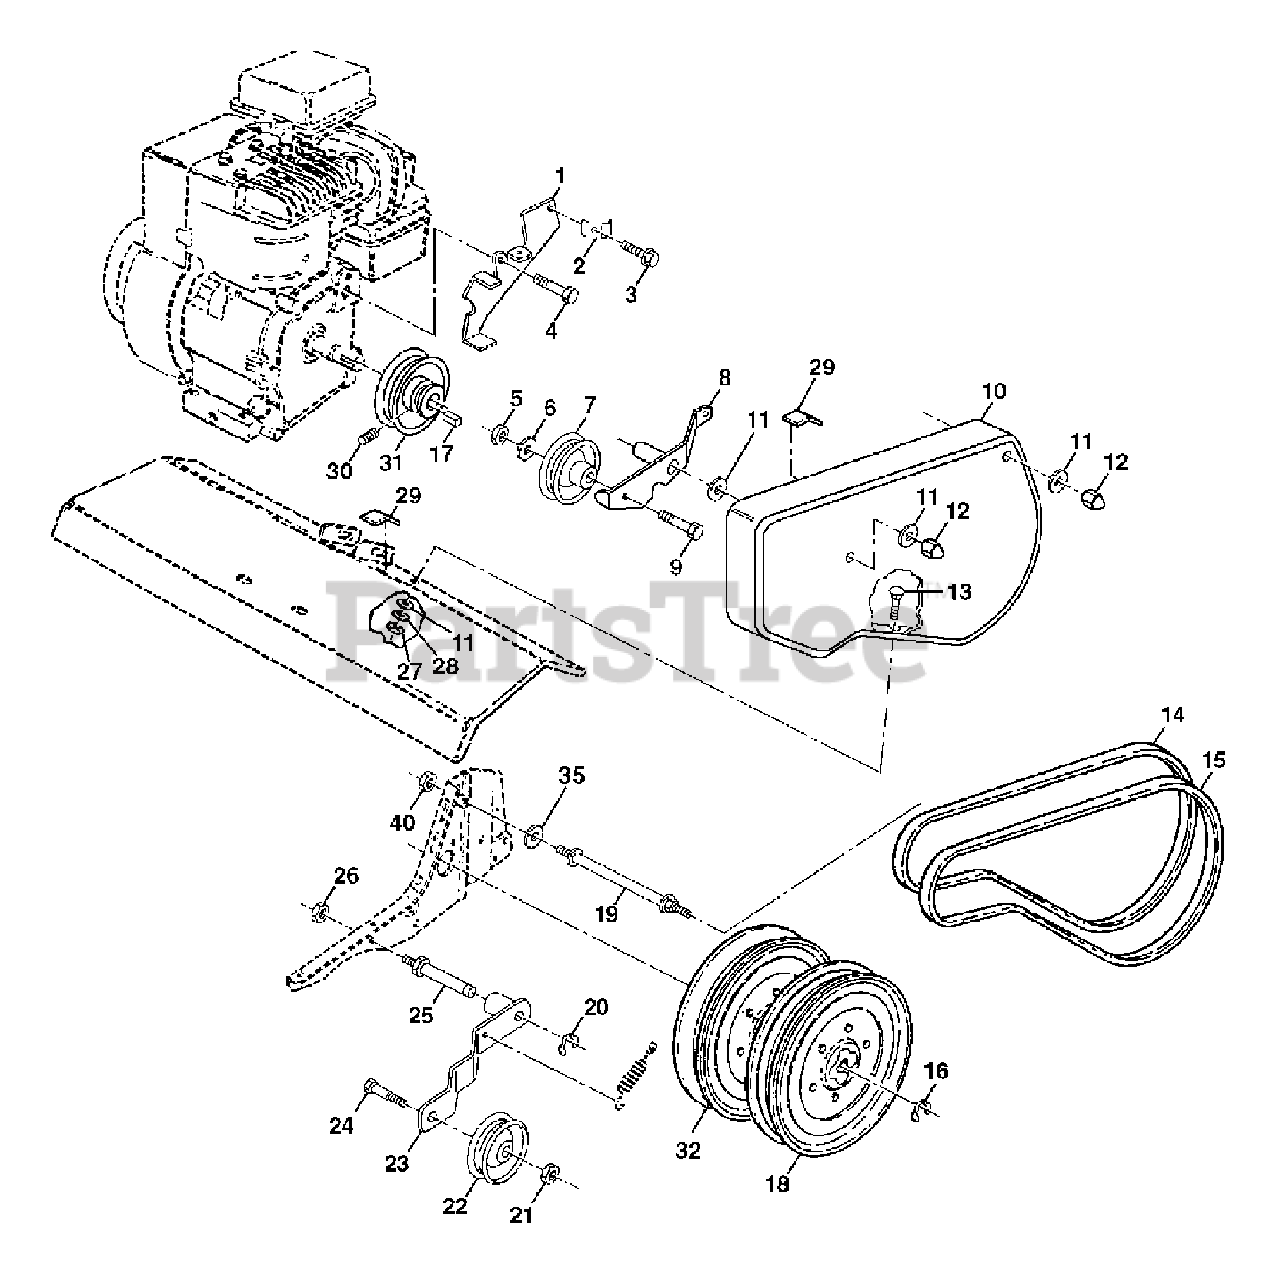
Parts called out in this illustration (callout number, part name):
1	Assembly, Bracket, Belt Guard
2	Clip, Cable
3	Screw, Hex, Washer Hd., Slotted, Thd. Cutting #10-24 x 1/2 Type D
4	Bolt, fin Hex 1/2-20 x 3/4
5	Nut, Hex 3/8-16
6	Washer 13/32 x 13/16 x 16 Ga.
7	Pulley, Idler, Reverse
8	Assembly, Arm, Reverse Idler
9	Bolt, Hex 3/8-16 x 1-3/4
11	Washer 9/32 x 5/8 x 16 Ga.
12	Nut, Cap 1/4-20
13	Bolt, Carriage 1/4-20 x 3/4
14	V-Belt (Forward Motion)
15	V-Belt (Reverse)
16	Ring, Retainer
17	Key, Square
18	Sheave, Transmission, Flat Rev.
19	Bolt, Belt Guard
20	Ring, Klip
21	Nut, Hex, Jam 3/8-16
22	Pulley, Idler
23	Arm, Idler
24	Bolt, Hex 3/8-16 x 1-1/4
25	Shaft, Idler Arm
26	Nut, Hex, Jam 5/16-18
27	Nut, Fin Hex 1/4-20
28	Washer Lock Hvy Helical 1/4
29	Pad, Idler
30	Screw, Set , Socket, Headless C.P. 1/4-20 x 1/4
31	Sheave, Engine
32	Sheave, Transmission "D"
35	Washer 9/32 x 7/8 x 16 Ga.
40	Nut Keps Hex 1/4-20
